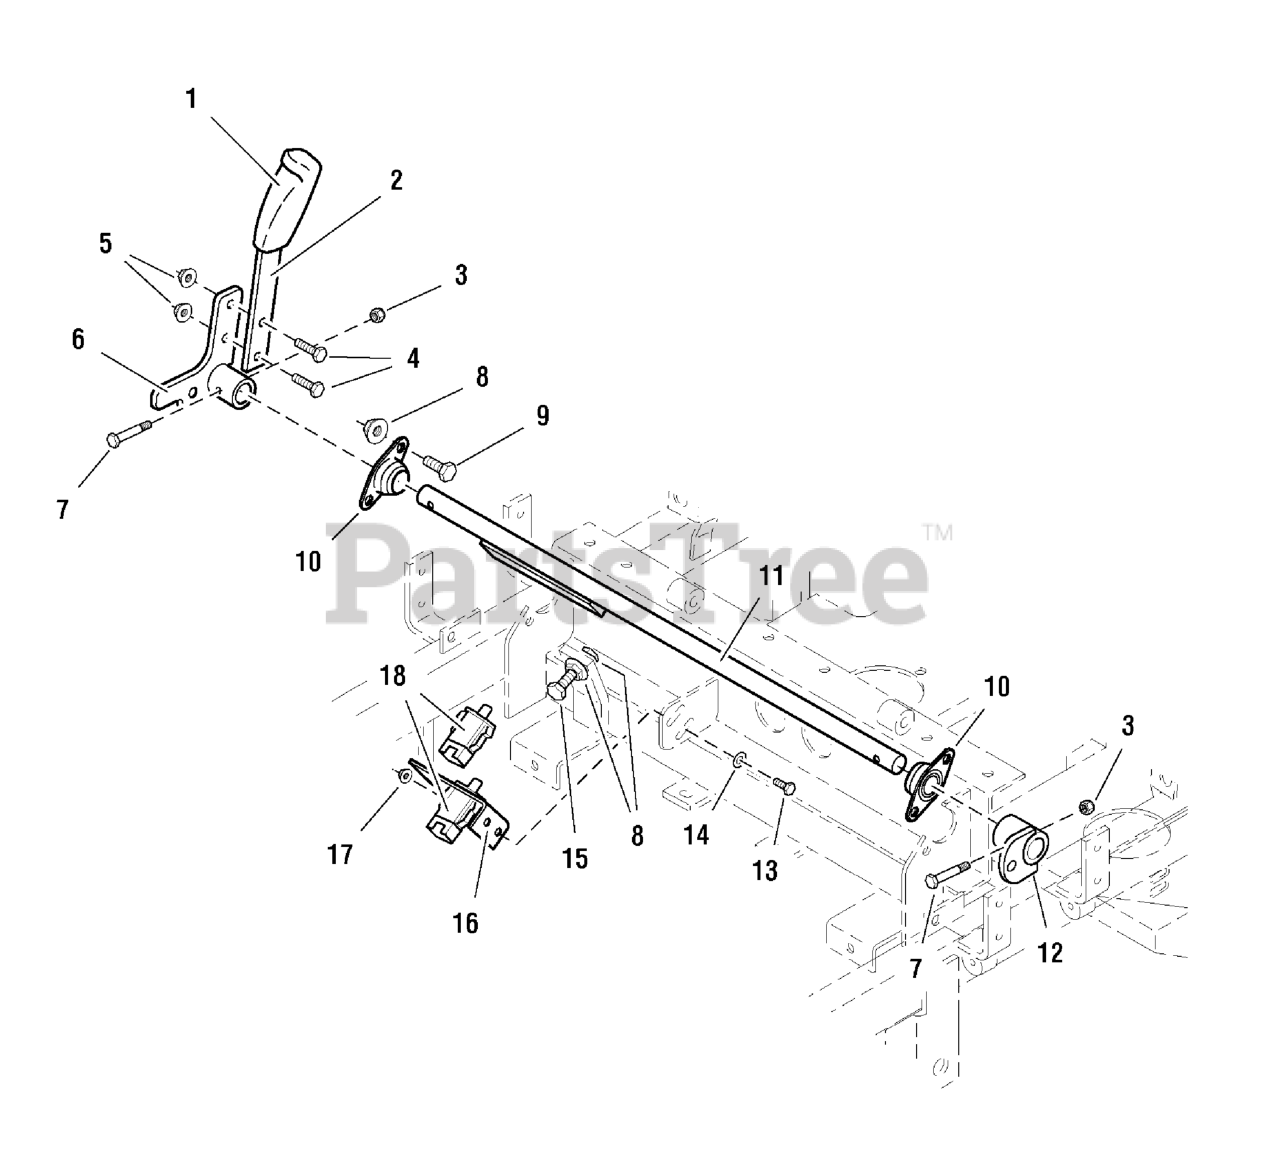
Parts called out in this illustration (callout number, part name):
1	GRIP
2	BRAKE HANDLE
3	NUT, 1/4-20 HEX NYLON LOCK
4	BOLT, 5/16-18 X 1 GD5 YZ
5	NUT, 5/16-18 HEX SERRATED FLANGE (SMALL)
6	BRAKE HANDLE MOUNT
7	BOLT, 1/4-20 x 1-3/4
8	NUT, 3/8-16 Hex Serrated Flange
9	BOLT, 3/8-16 X 3/4" GD5 CZ
10	BEARING, Flange
11	BRAKE HANDLE SHAFT
12	PIVOT, LINKAGE MOUNT WELDMENT - BLK
13	BOLT, 1/4-20 x 3/4
14	WASHER, 1/4 SAE
15	BOLT, 3/8-16 x 1-3/4 TFL
16	SWITCH MOUNT BRACKET
17	NUT, 1/4-20 HEX SERR. FLANGE
18	SWITCH (see electrical group)
